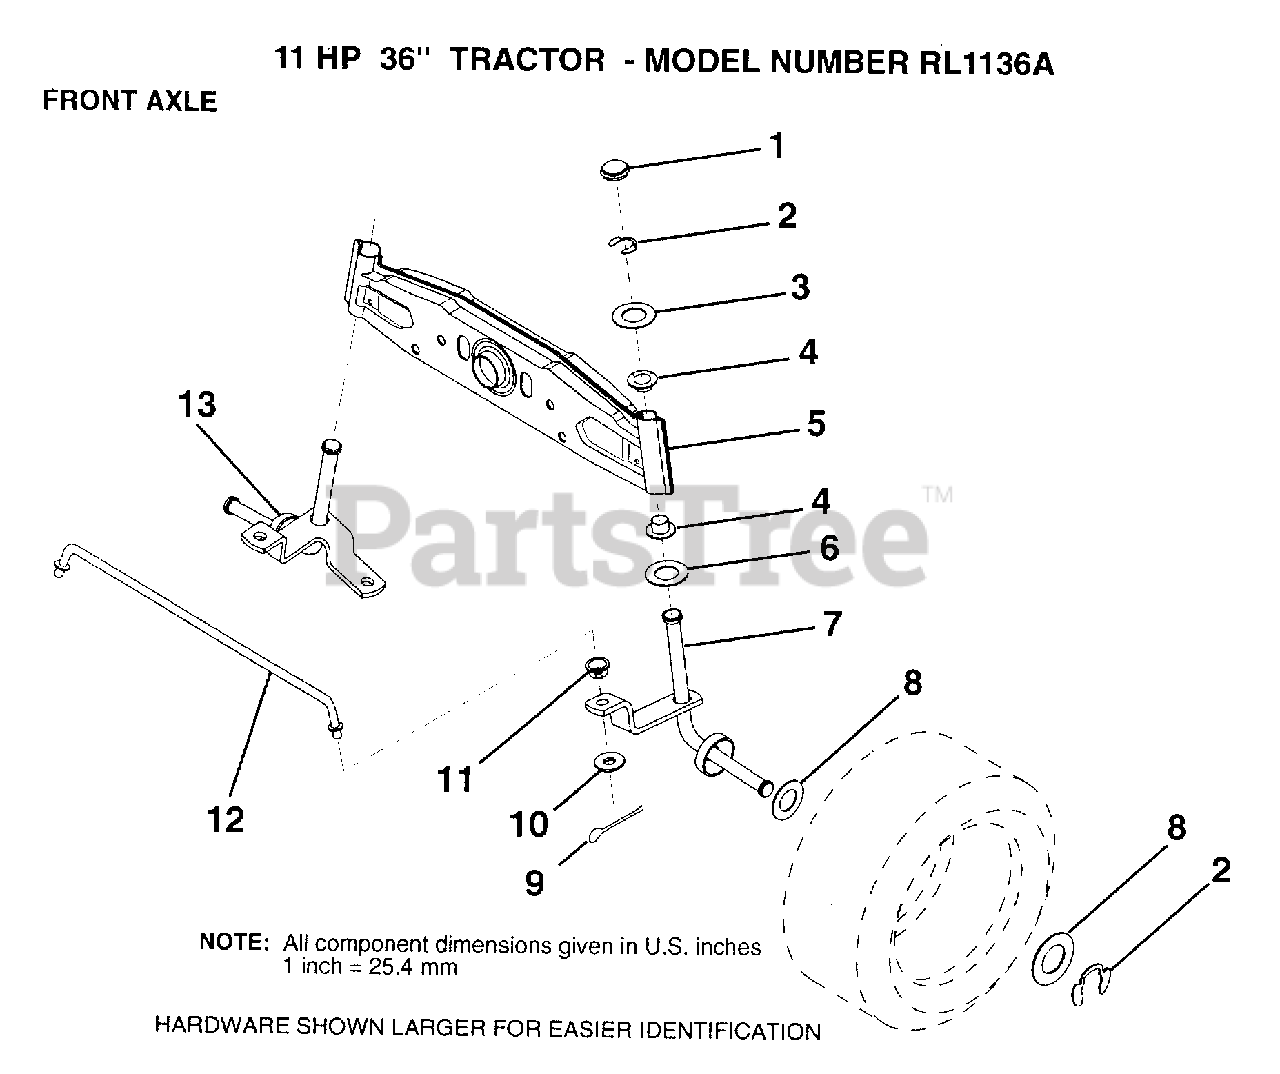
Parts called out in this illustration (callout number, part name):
1	CAP
2	RING
3	WASHER
4	NYLINER
5	AXLE FRONT
6	WASHER .T
7	SPINDLE RH
8	WASHER
9	COTTER PIN
10	WASHER
11	BUSHING.DRAGLINK
12	ROD TIE
13	SPINDLE LH
